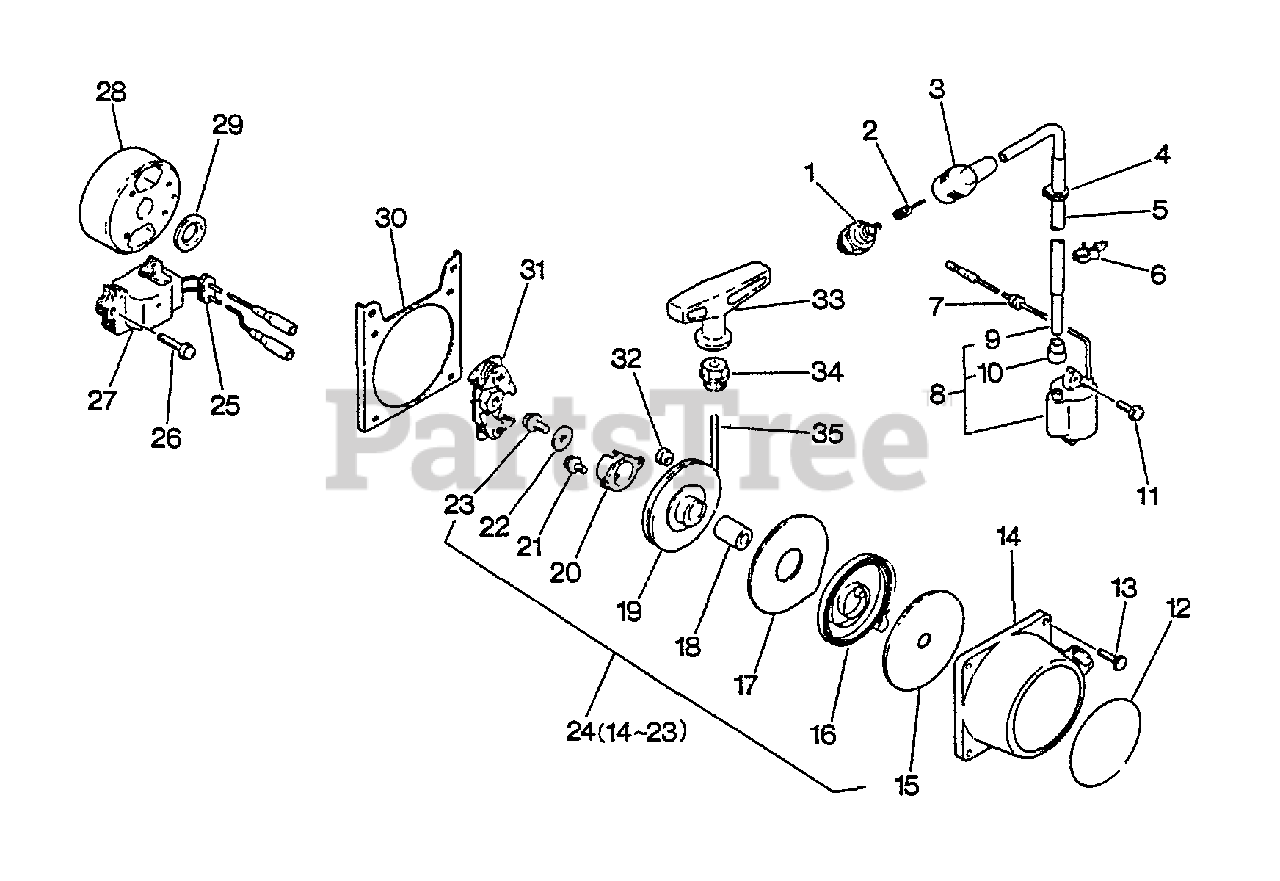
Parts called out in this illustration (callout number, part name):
1	SPARK PLUG -- BPM-7A
2	TERMINAL, SPARK PLUG CAP
3	CAP, SPARK PLUG
8	IGNITION COIL ASSY
9	CORD, HIGH TENSION
10	CORD, HIGH TENSION
11	SCREW - 4X14
12	LABEL - ECHO
13	SCREW - 4X16
14	CASE, STARTER
15	PLATE, STARTER
16	SPRING, REWIND
17	PLATE, STARTER
19	REEL, ROPE
20	CATCHER, PAWL
21	SCREW - 4X8
22	WASHER - 5
23	SCREW - 5X10
24	STARTER ASSY
26	SCREW - 4X20
27	COIL, IGNITION
28	FLYWHEEL
31	STARTER PAWL ASSY
32	RETAINER, ROPE
33	GRIP, STARTER
34	GUIDE, ROPE
35	ROPE, STARTER - 3.5X850
